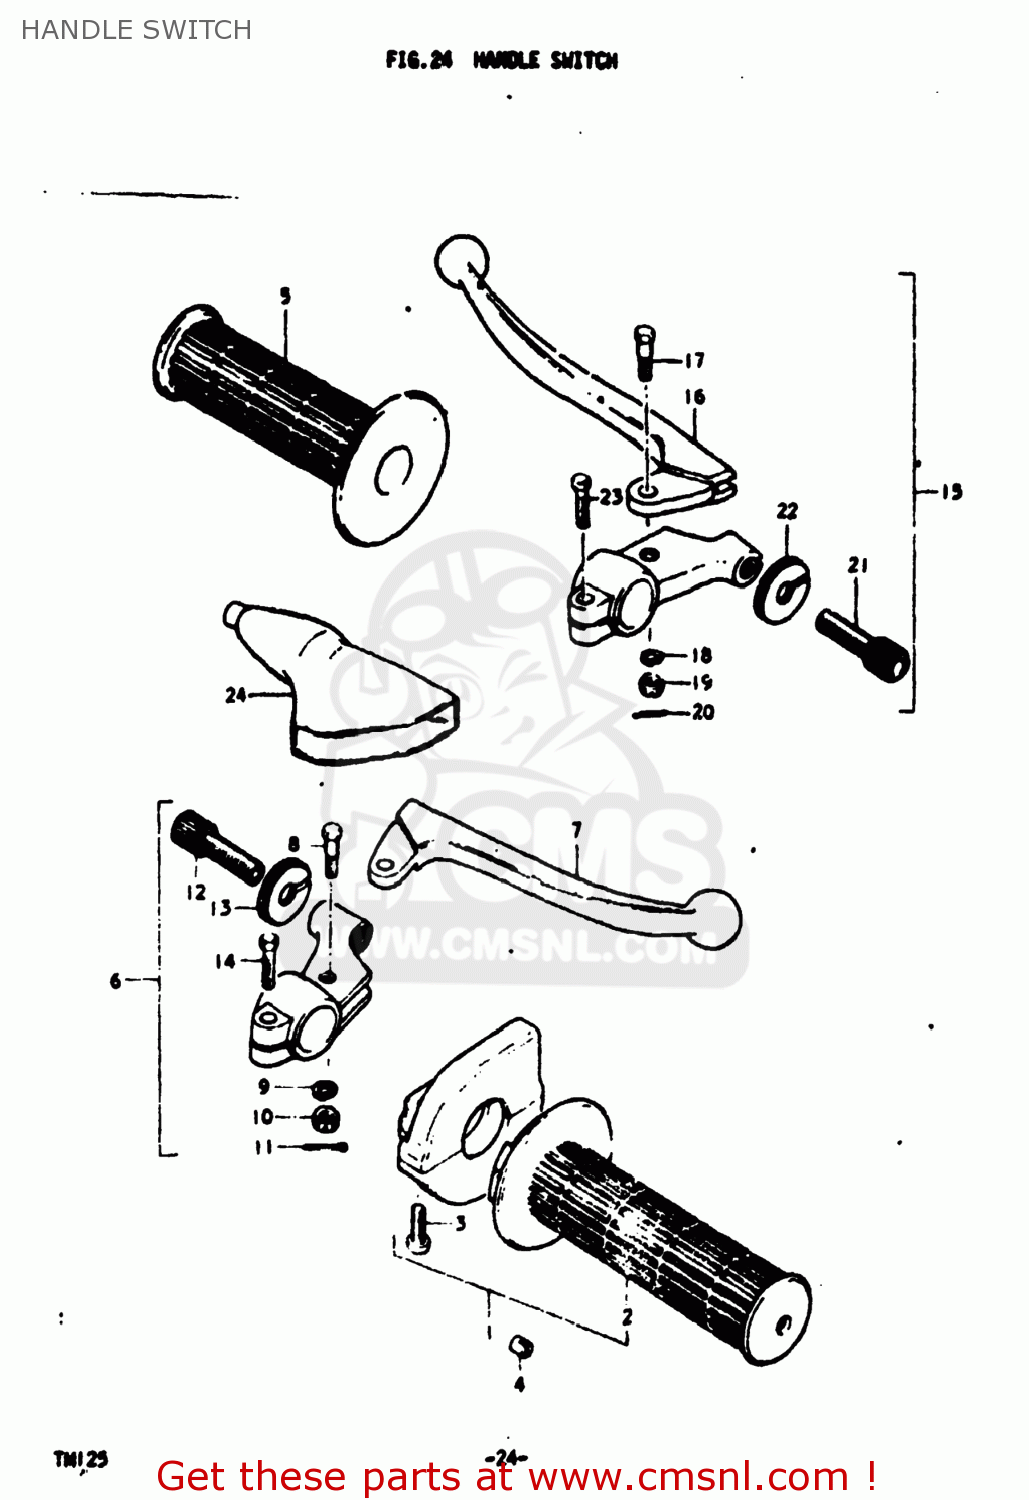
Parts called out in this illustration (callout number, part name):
1	CASE ASSEMBLY,THROTTLE
2	GRIP,THROTTLE
3	SCREW
4	PIECE,THROTTLE END
5	GRIP,LEFT
6	LEVER ASSEMBLY,BRAKE
7	LEVER,BRAKE
8	BOLT,LEVER
9	LOCK WASHER
10	NUT,LEVER FITTNG
11	COTTER PIN
12	ADJUSTER,CABLE
13	NUT,CABLE ADJUSTER
14	BOLT
15	LEVER ASSEMBLY
16	LEVER,CLUTCH
17	BOLT
18	LOCK WASHER
19	NUT,LEVER FITTNG
20	COTTER PIN
21	ADJUSTER,CABLE
22	NUT,CABLE ADJUSTER
23	BOLT
24	COVER,CLUTCH LEVER
